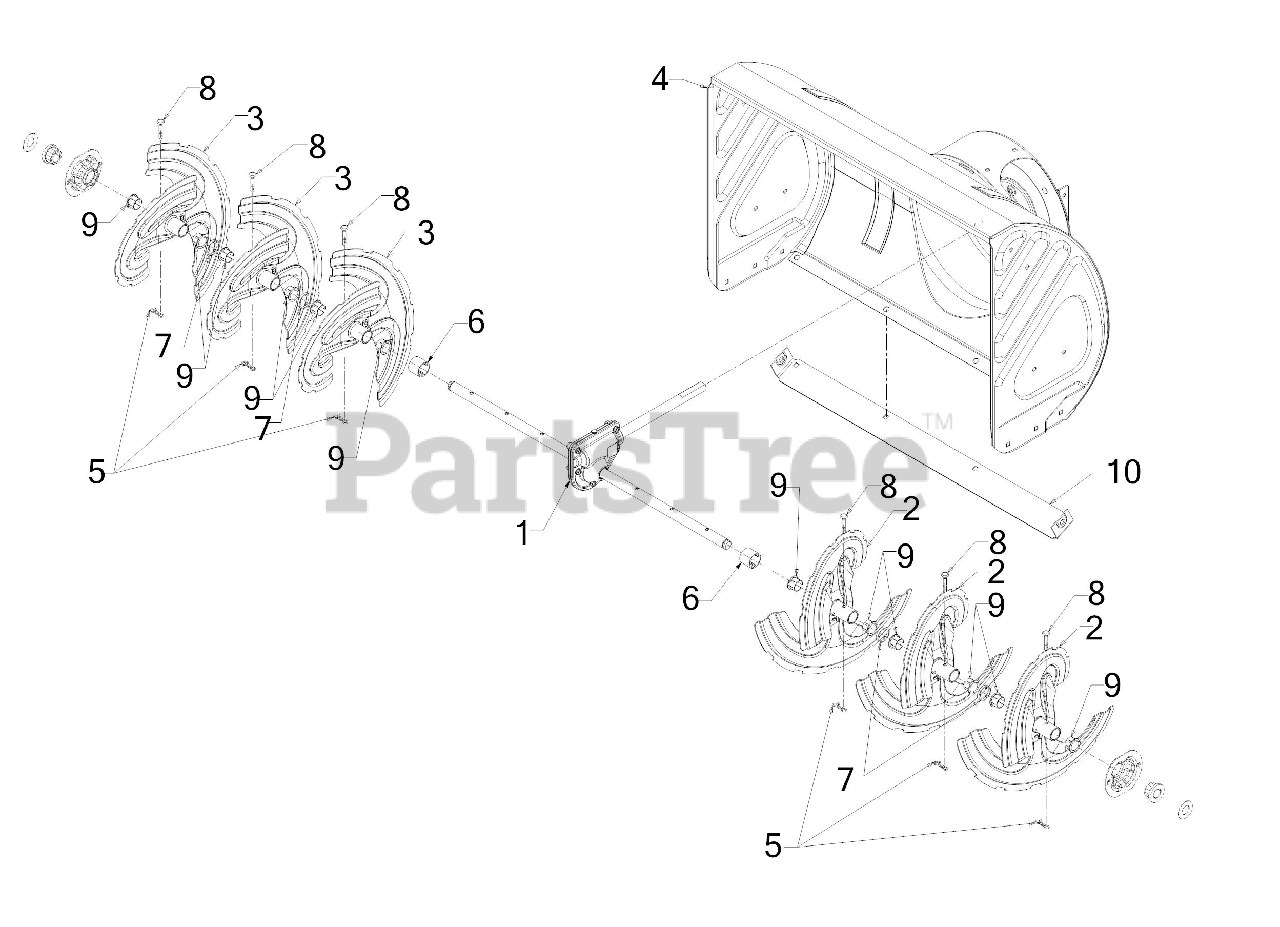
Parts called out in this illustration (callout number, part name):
1	30" GEARBOX ASSEMBLY
2	AUGER ASSEMBLY (LH)
3	AUGER ASSEMBLY (RH)
4	30" AUGER HOUSING
5	BOW TIE COTTER PIN 1/4-5/16
6	SPACER 1.25OD x .75ID X1.00 LG
7	SPCR 1.25 OD x 75IDX2.00LG
8	SHEAR PIN .25 x 1.50 GR2
9	FLANGE BUSHING
10	30" SHAVE PLATE
